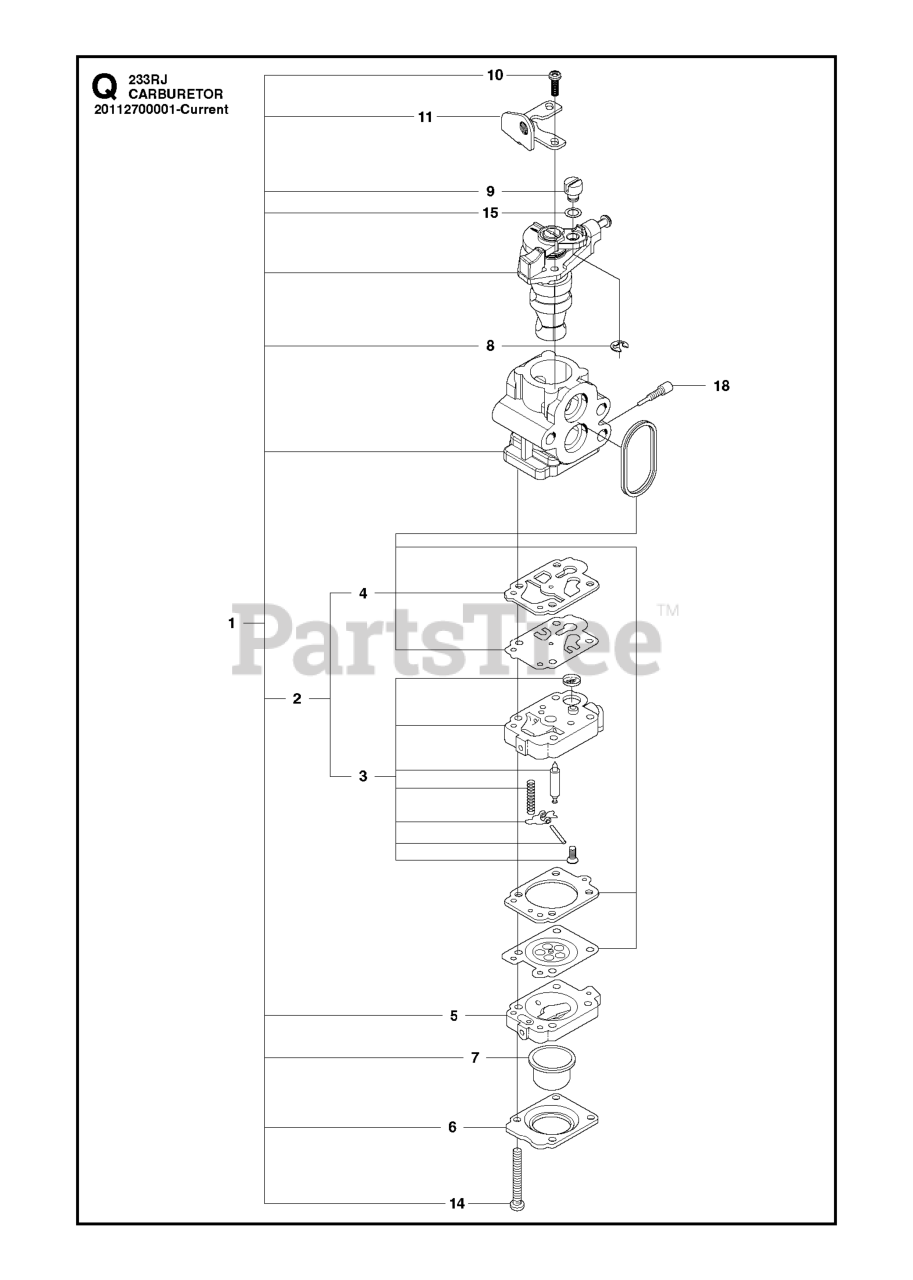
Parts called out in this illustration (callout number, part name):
2	REBUILD KIT
3	CARBURETOR BODY
4	GASKET KIT
